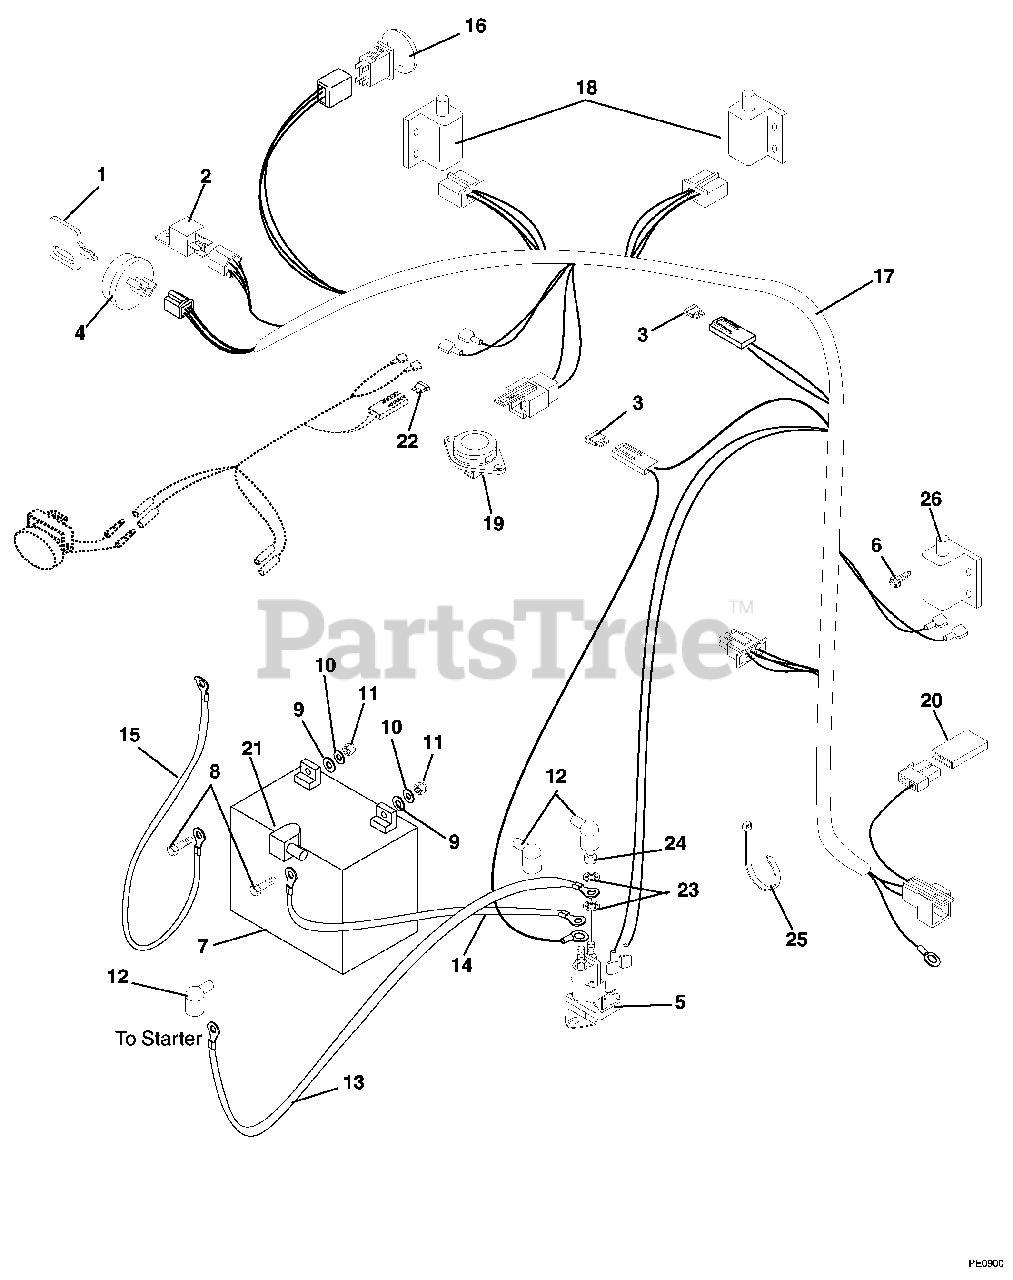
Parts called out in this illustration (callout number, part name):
1	Key with Cap
2	Relay
3	Fuse, 25 AMP
4	Key Switch
5	Solenoid
6	Screw, Tapping 10- 24 x .50 Hex Washer Head
7	Battery, Filled (034, 036, 038, 040)
7	Battery with Tube
8	Bolt, Hex .25-20 x .75 Grade 5
9	Washer, Flat Steel .281 x .62 x .065
10	Washer, Locking .25 x .062 Regular
11	Nut, Hex .25-20
12	Boot, Eyelet Terminal
13	Starter Cable 22"
14	Starter Cable 13"
15	Ground Cable
16	Switch, Clutch With Retainer
17	Wire Harness, Zoom 6 Pin
18	Switch, Double Pole N.O./N.O.
19	Switch, Snap Mounting (N.O.)
20	Diode, Connector Shell
21	Insulator
22	Fuse, 10 AMP
23	Washer, Locking .31
24	Nut, Jam .31-24
25	Cable Tie
26	Switch, Interlock NC
